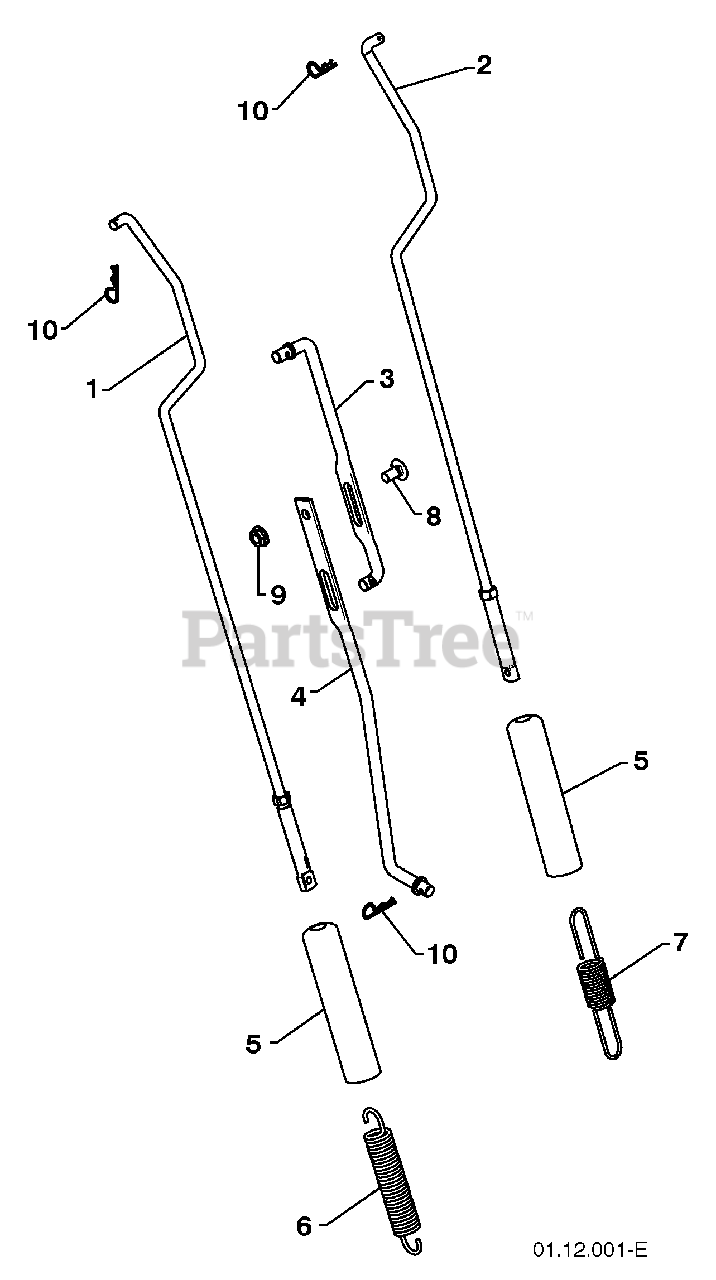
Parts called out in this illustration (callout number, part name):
1	IMPELLER ROD ASSEMBLY
2	TRACTION ROD ASSEMBLY
3	SHIFTER ROD TOP
4	SHIFTER ROD BOTTOM
5	SPRING SLEEVE
6	IMPELLER SPRING
7	TRACTION SPRING
8	CARRIAGE BOLT 5/16-18 X .75
9	NUT 5/16-18
10	RETAINER
